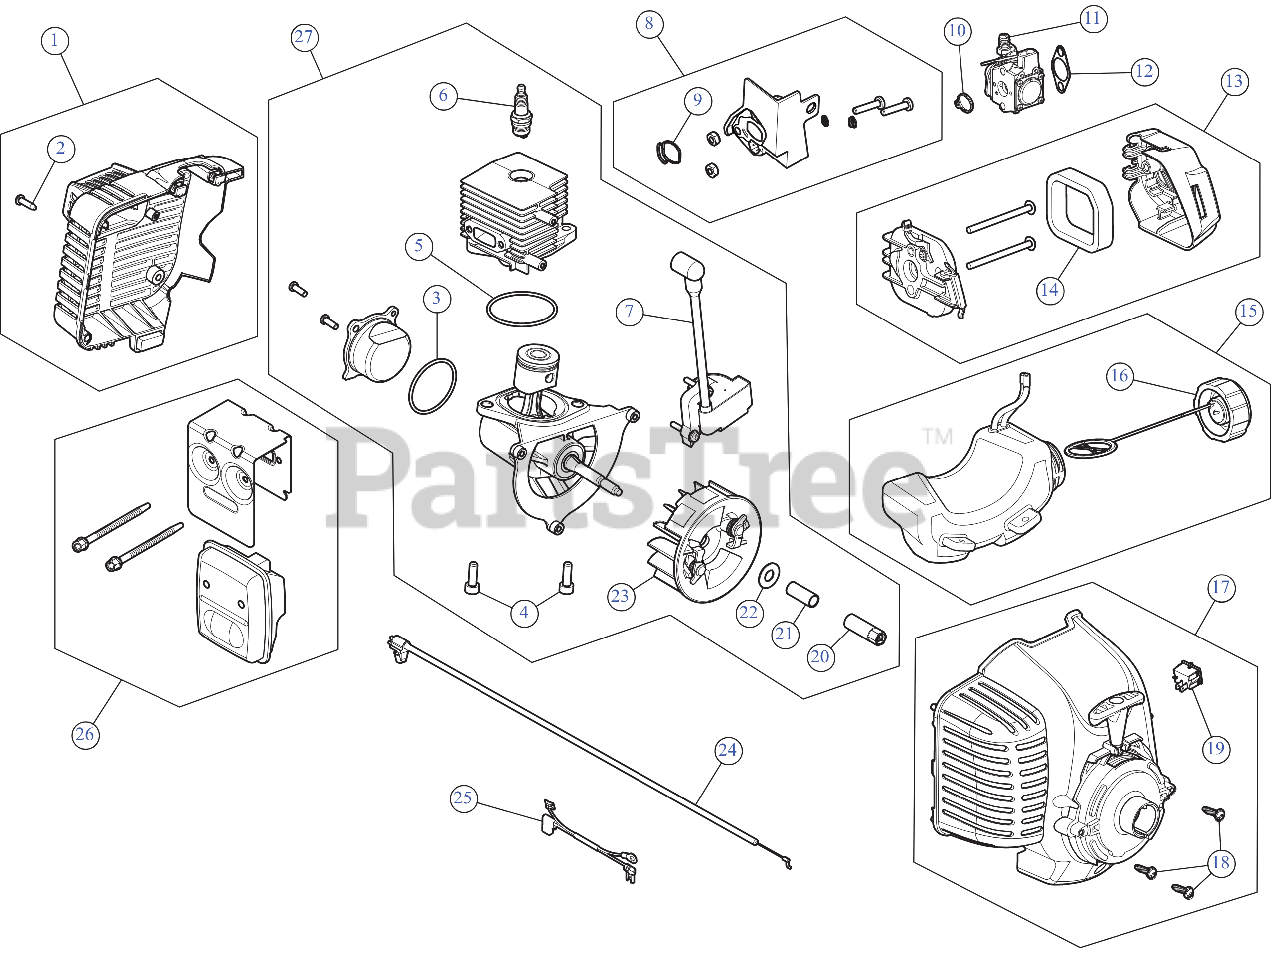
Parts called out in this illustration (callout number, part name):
1	HOUSING ASSEMBLY RR
2	SCREW 8-16 x 3/4
3	O-RING SEAL CRANKCASE
4	SCREW 5/16-18x3/4 T40
5	O-RING SEAL CYLINDER
6	SPARK PLUG
7	MODULE ASSEMBLY
8	INTAKE ASSEMBLY
9	INSL/CYL SEAL
10	CARBURETOR SEAL
11	CARB ASSEMBLY
12	GASKET CARB
13	AIR CLEANER
14	AIR FLITER
15	FUEL TANK ASSEMBLY
16	FUEL CAP ASSEMBLY
17	STARTER HOUSING
19	SW, MOMENTARY ON/O
20	POWER SHAFT ADAPTER
21	SPACER CRANKSHAFT
22	BELL WASHER
23	FLYWHEEL ASSEMBLY
24	THROTTLE CABLE
25	SHORT WIRE LEAD
26	MUFFLER ASSEMBLY
27	SHORT BLOCK
